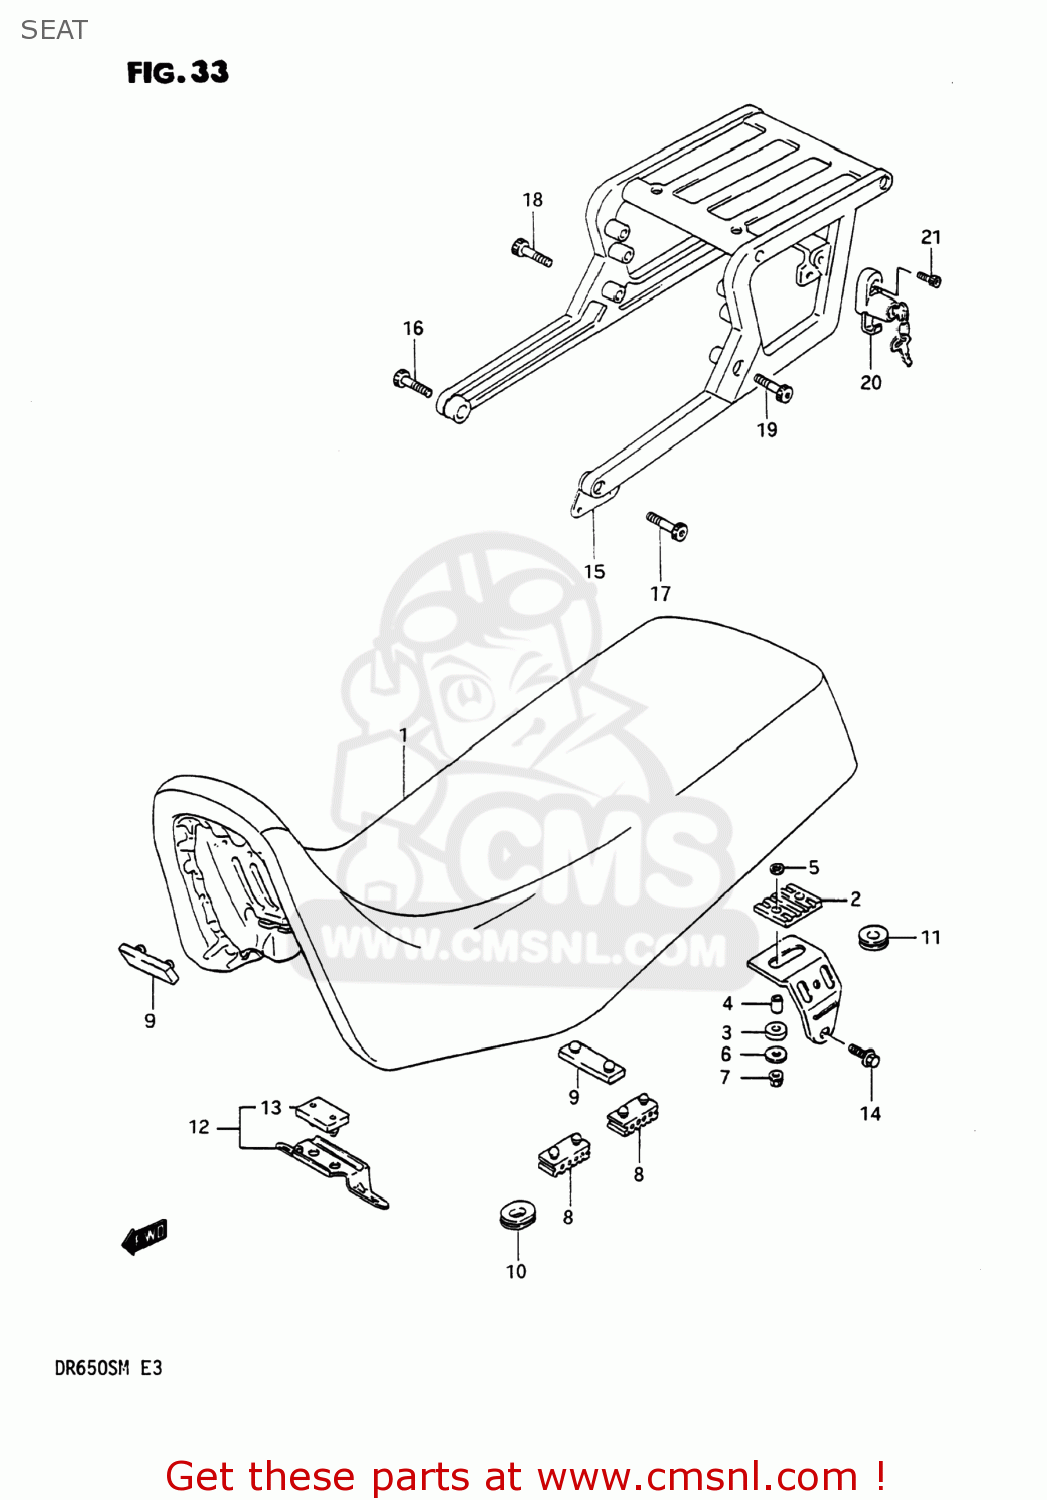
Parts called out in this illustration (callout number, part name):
1	SEAT SET
2	CUSHION,SEAT FR
3	CUSHION,FR PLATE
4	SPACER,SEAT SUPPORT
5	WASHER
6	WASHER, LOWER
7	NUT
8	CUSHION,SEAT(40X20X15)
9	CUSHION
10	CUSHION
11	CUSHION
12	PLATE ASSY,SEAT FR HOOK
13	CUSHION
14	BOLT, 8X1.25X1
15	CARRIER ASSEMBLY,REAR
16	BOLT, FRONT RH
17	BOLT, FRONT LH
18	BOLT, REAR RH
19	BOLT ,8X50
20	LOCK SET,HELMET
21	BOLT
